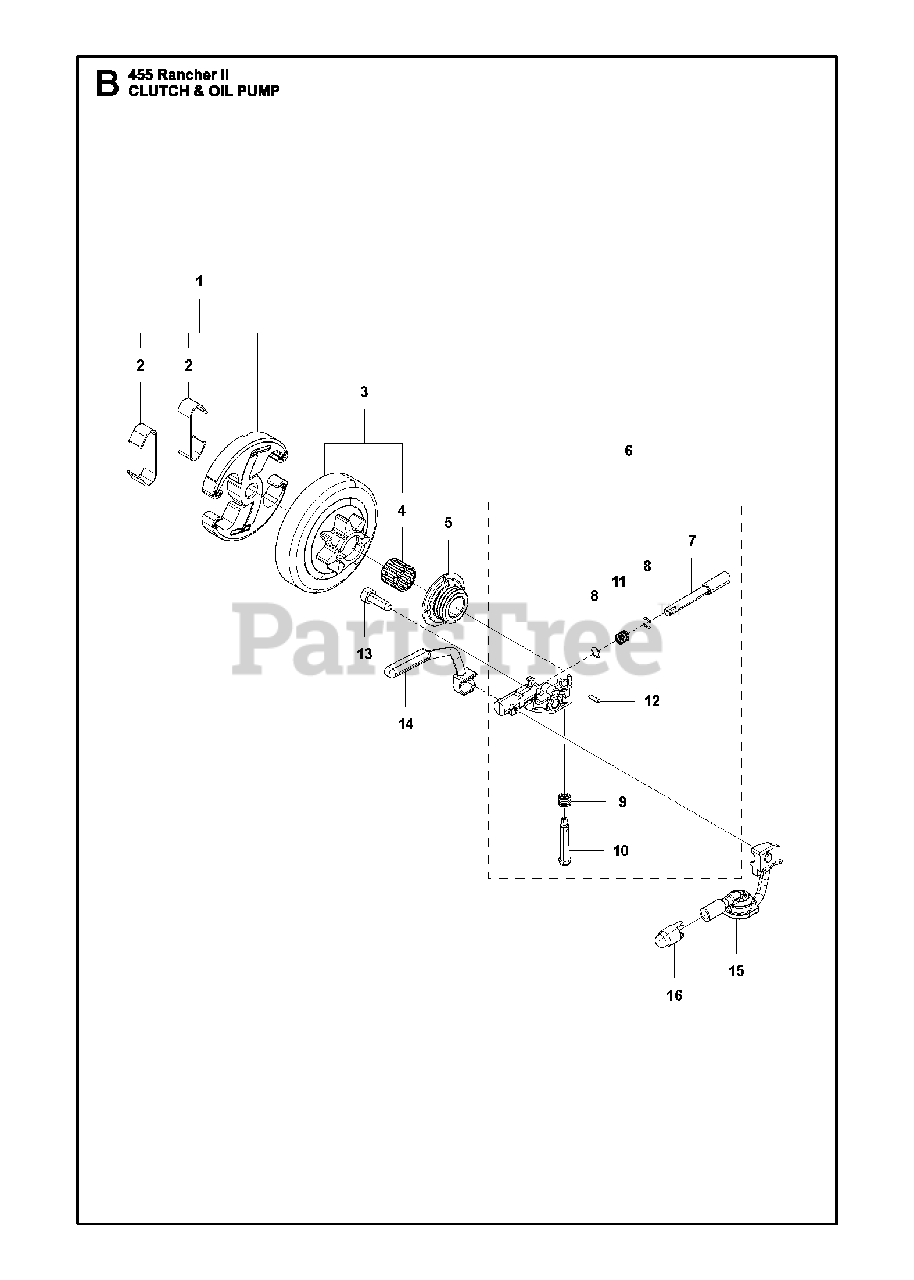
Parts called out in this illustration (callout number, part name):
2	SPRING
3	CLUTCH DRUM
4	NEEDLE BEARING
5	GEAR WORM OILER
6	OIL PUMP ASSY
7	PUMP PISTON
8	WASHER
9	SPRING
10	ADJUSTER
11	SPRING
12	PIN
13	SCREW
16	OIL SCREEN
